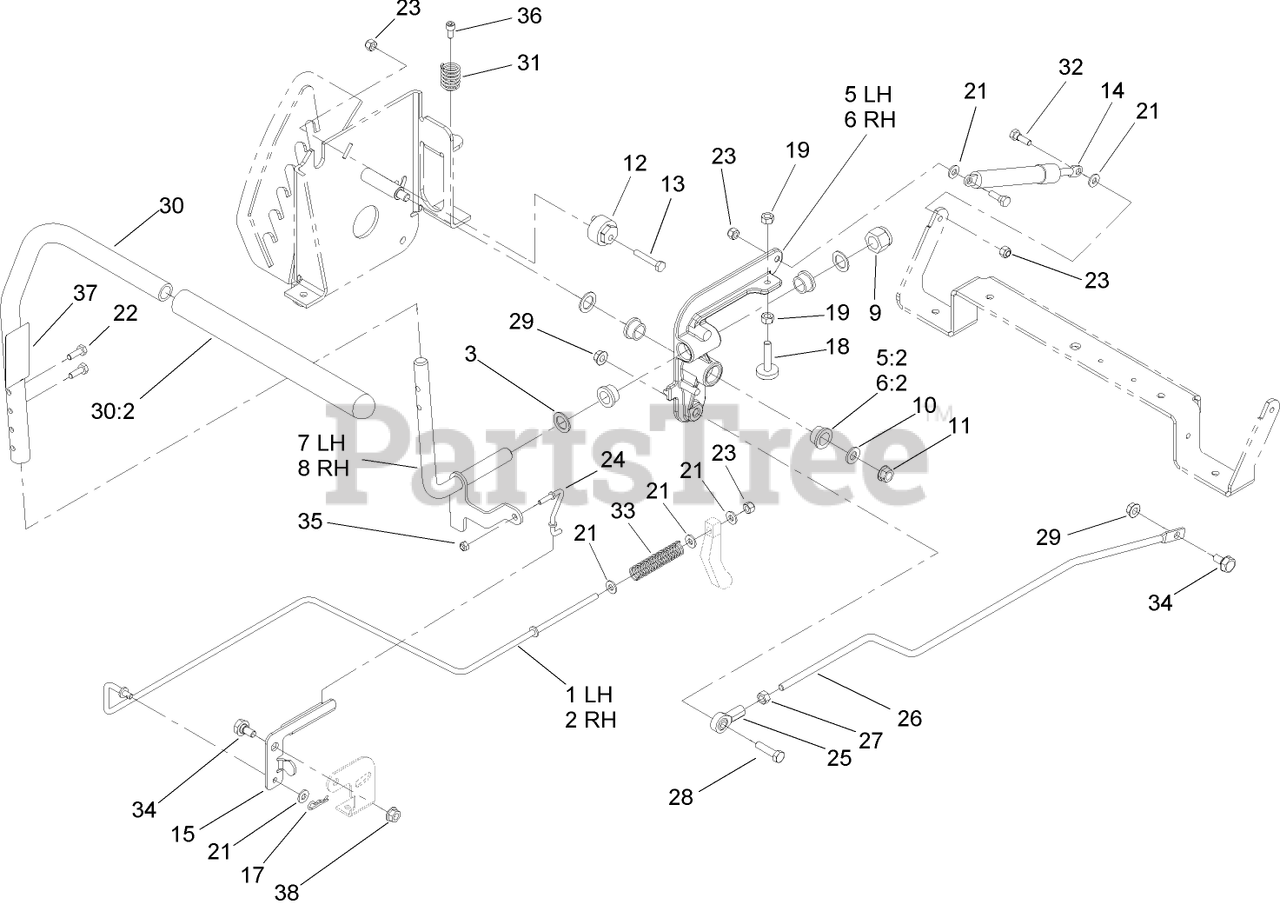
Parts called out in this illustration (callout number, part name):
2	ROD-BRAKE, RH
3	WASHER-THRUST
6:2	BUSHING
8	RH PIVOT SHAFT ASM
9	NUT-LOCK, NI
10	WASHER-FLAT
12	ECCENTRIC
13	SCREW-HH
15	BELLCRANK
17	PIN-COTTER
18	STOP-ADJUSTMENT
19	NUT-HEX
21	WASHER-FLAT
22	SCREW-HH
23	NUT-LOCK, NI
24	LINK-BRAKE
25	BALLJOINT-RH
26	ROD-HYDRO
27	NUT-HEX
28	SCREW-HH
29	NUT-HF
30	HANDLE ASM
30:2	GRIP-CONTROL, MOTION
31	SPRING-COMPRESSION
32	BOLT-SHOULDER
33	SPRING-COMPRESSION
34	BOLT-SHOULDER,HFH
35	NUT-LOCK, NI
36	SCREW-HSH
38	NUT-HF
